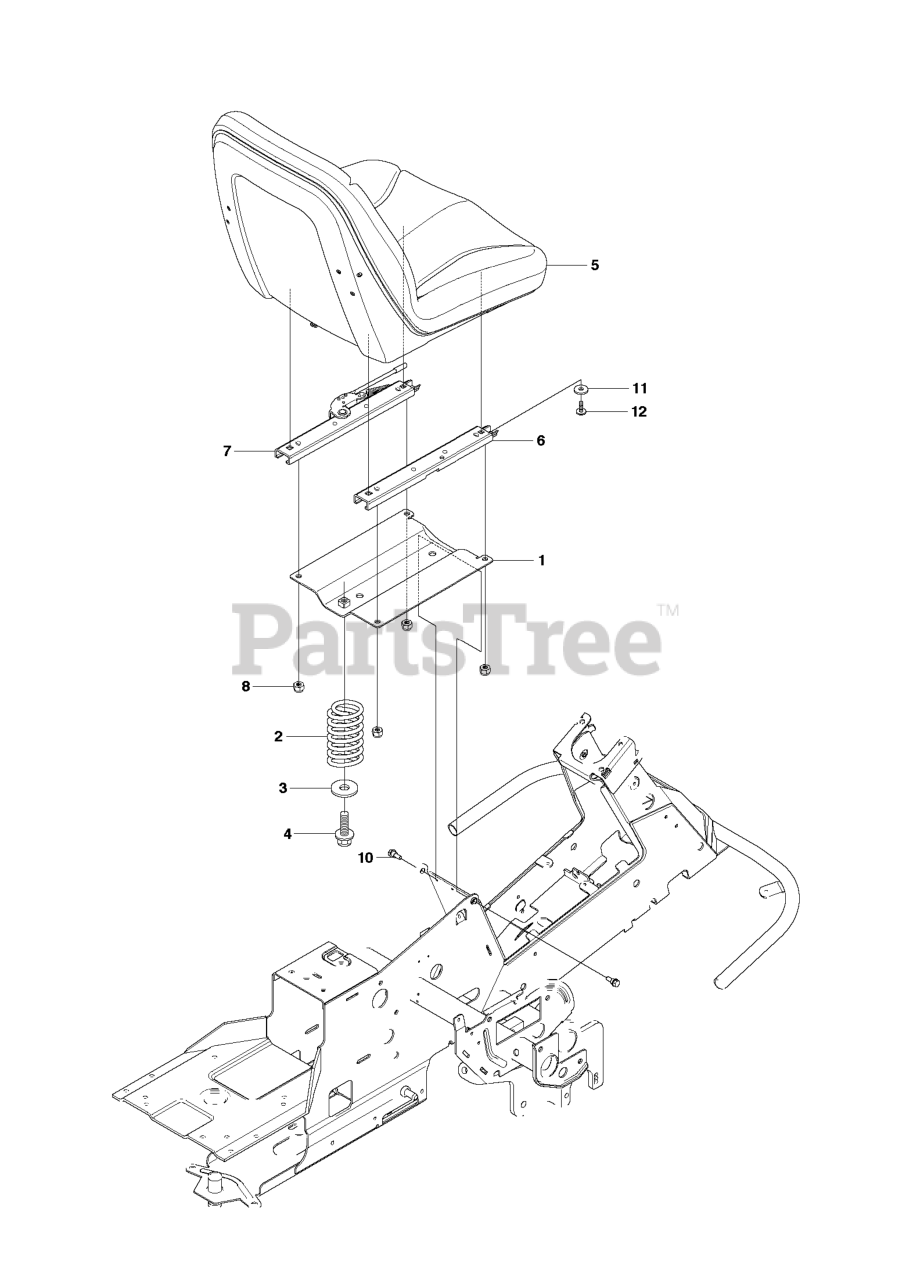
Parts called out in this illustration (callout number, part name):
1	SEAT BRACKET
2	SEAT SPRING
4	Screw M10x25
5	SEAT
8	LOCKNUT M8
11	WASHER
12	BOLT.FIN.HEX.5/16-18X3/4
